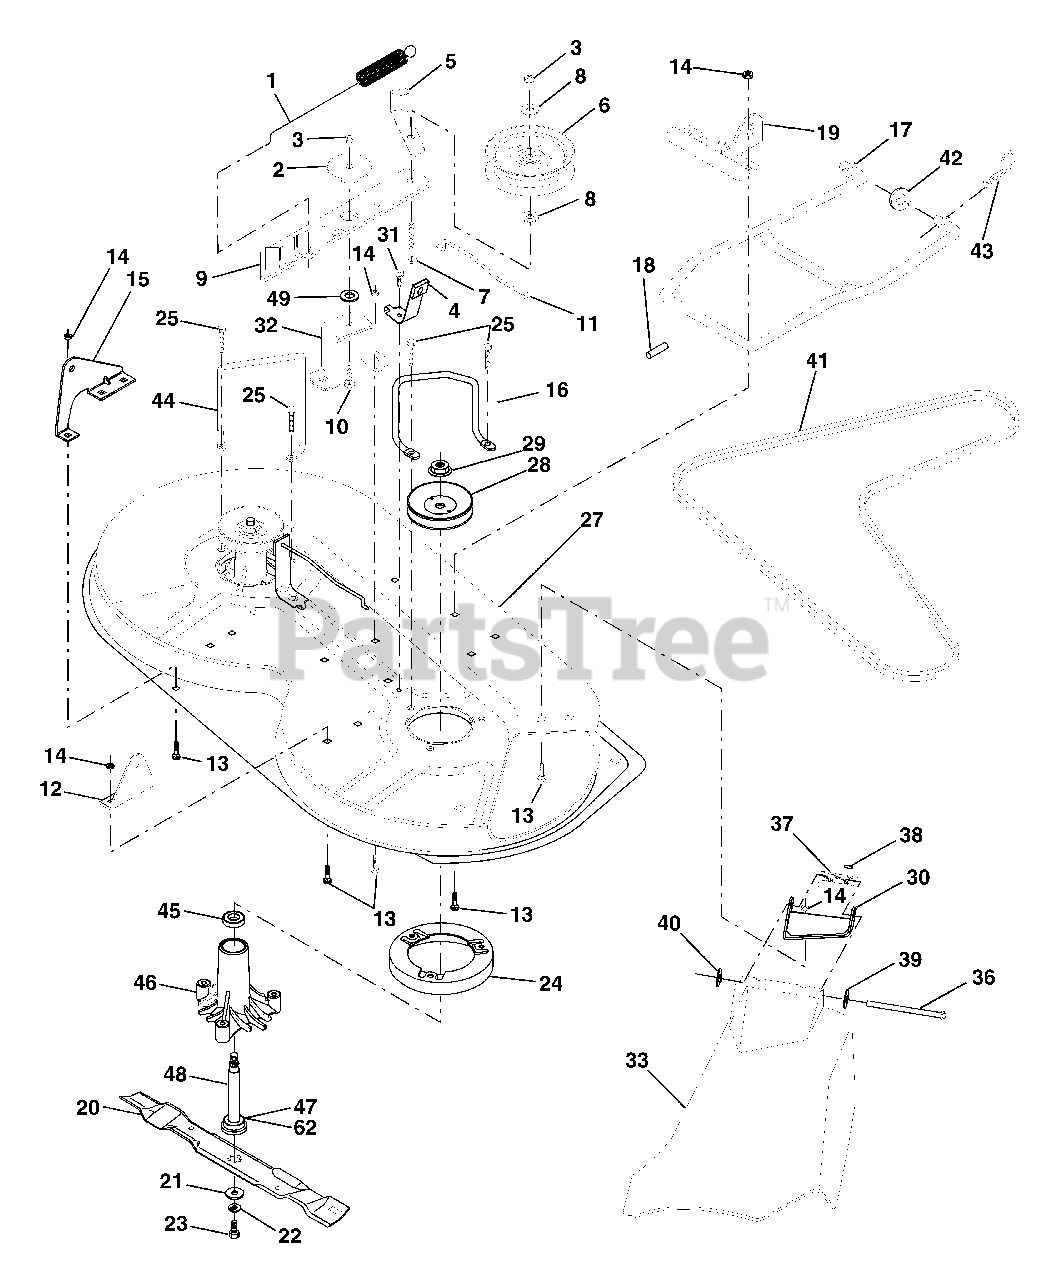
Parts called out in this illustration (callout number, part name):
1	Spring, Mower Clutch
2	Spacer, Retainer
3	Nut, Crownlock 3/8-16
4	Brake Asm.
5	Guide, Belt Idler
6	Pulley, Flat Idler
7	Bolt, Carr. 3/8-16 x 1-3/4 Gr. 5
8	Washer 13/21 x 7/8 x 10 Ga.
9	Arm Asm., Idler Mower
10	Bolt, Carriage 3/8-16 x 1-1/4
11	Rod, Brake
12	Bracket, Lift R.H. Rear
13	Bolt, Carriage 5/16-18 x 3/4
14	Nut, Crownlock 5/16-18
15	Bracket, Lift L.H. Rear
16	Keeper, R.H.
17	Link, Asm. Mower Stabilizer
18	Pin, Drive
19	Bracket, Asm. Front
20	Blade High Lift
21	Washer, Hardened
22	Washer, Lock 3/8
23	Bolt 3/8-24 x 1-1/4 Gr. 8
24	Stripper
25	Screw Thdrol Hex Hd
27	Deck Assembly
28	Pulley, Mandrel
29	Nut, Flange Lock 9/16
30	Bracket, Asm. Deflector
31	Screw, Hex Wsh. Thdrol. 5/16-18 x 1/2
32	Arm, Support Idler Mower
33	Deflector
36	Rod, Hinge
37	Spring, Torsion Deflector
38	Cap, Sleeve
39	Washer 11/32 x 5/8 x 16 Ga.
42	Washer 11/32 x 5/8 x 16 Ga.
43	Retainer, Spring
44	Keeper, L.H.
46	Housing Mandrel Vented
48	Shaft, Mandrel
49	Washer Hardened
62	Washer, Felt
